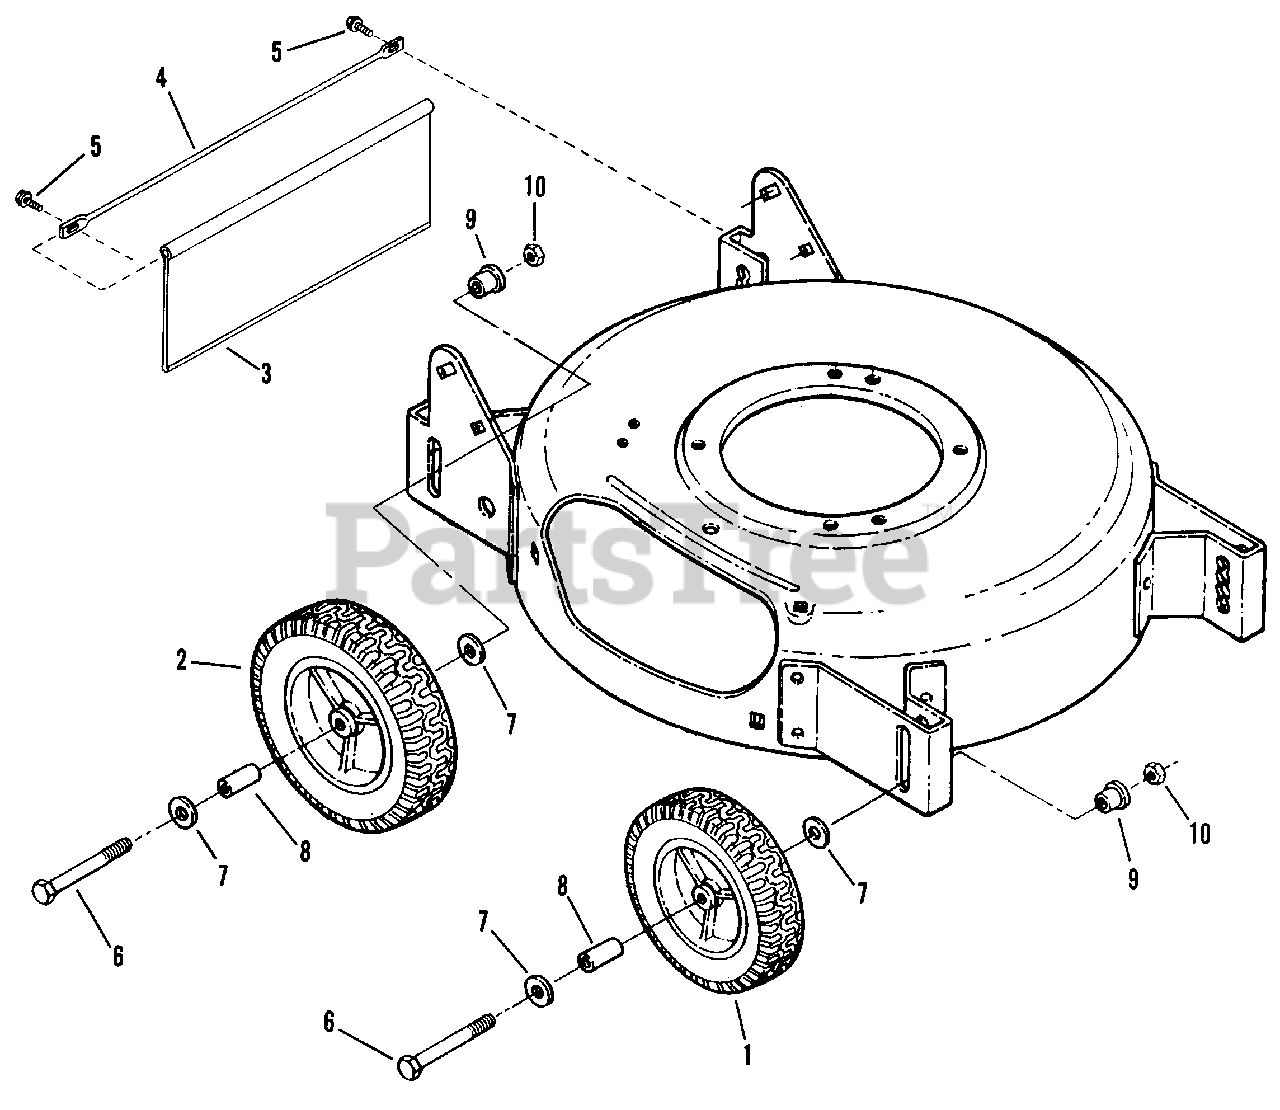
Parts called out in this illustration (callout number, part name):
1	WHEEL, Front 7 x 1.75 (2)
2	WHEEL, Rear 8 x 2.00 (2)
3	GUARD, Rear Foot
4	SUPPORT, Foot Guard
5	SCREW, #10-24 x 1/2" Hex Washer Self-Tap (Torx)
6	SCREW, 3/8-16 x 3-1/8" Hex Head Cap
7	WASHER, 3/8" Flat
8	BUSHING, Axle
9	BUSHING, Height Adjustment
10	NUT, 3/8-16 Hex Center Lock
